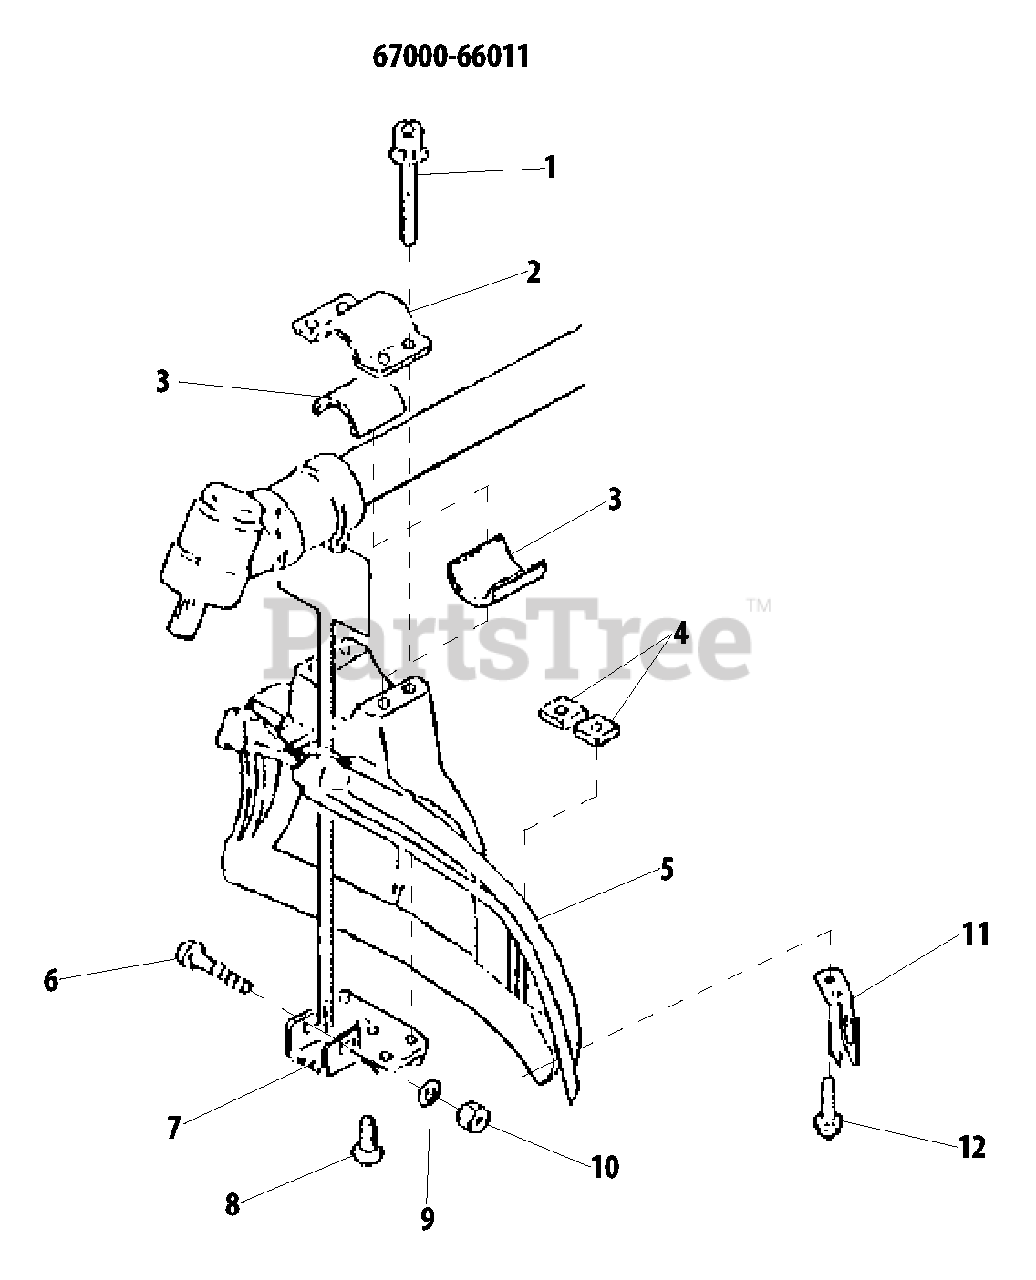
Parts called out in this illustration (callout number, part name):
1	SCREW - 5X45
2	CLAMP - UPPER
3	SPACER
4	NUT - 5
5	GUARD
6	SCREW - 5X35
7	CLAMP - LOWER
8	SCREW
9	WASHER - 5
11	KNIFE, TRIMMER LINE
12	SCREW - 5X16
67000-66011	DEBRIS SHIELD KIT
